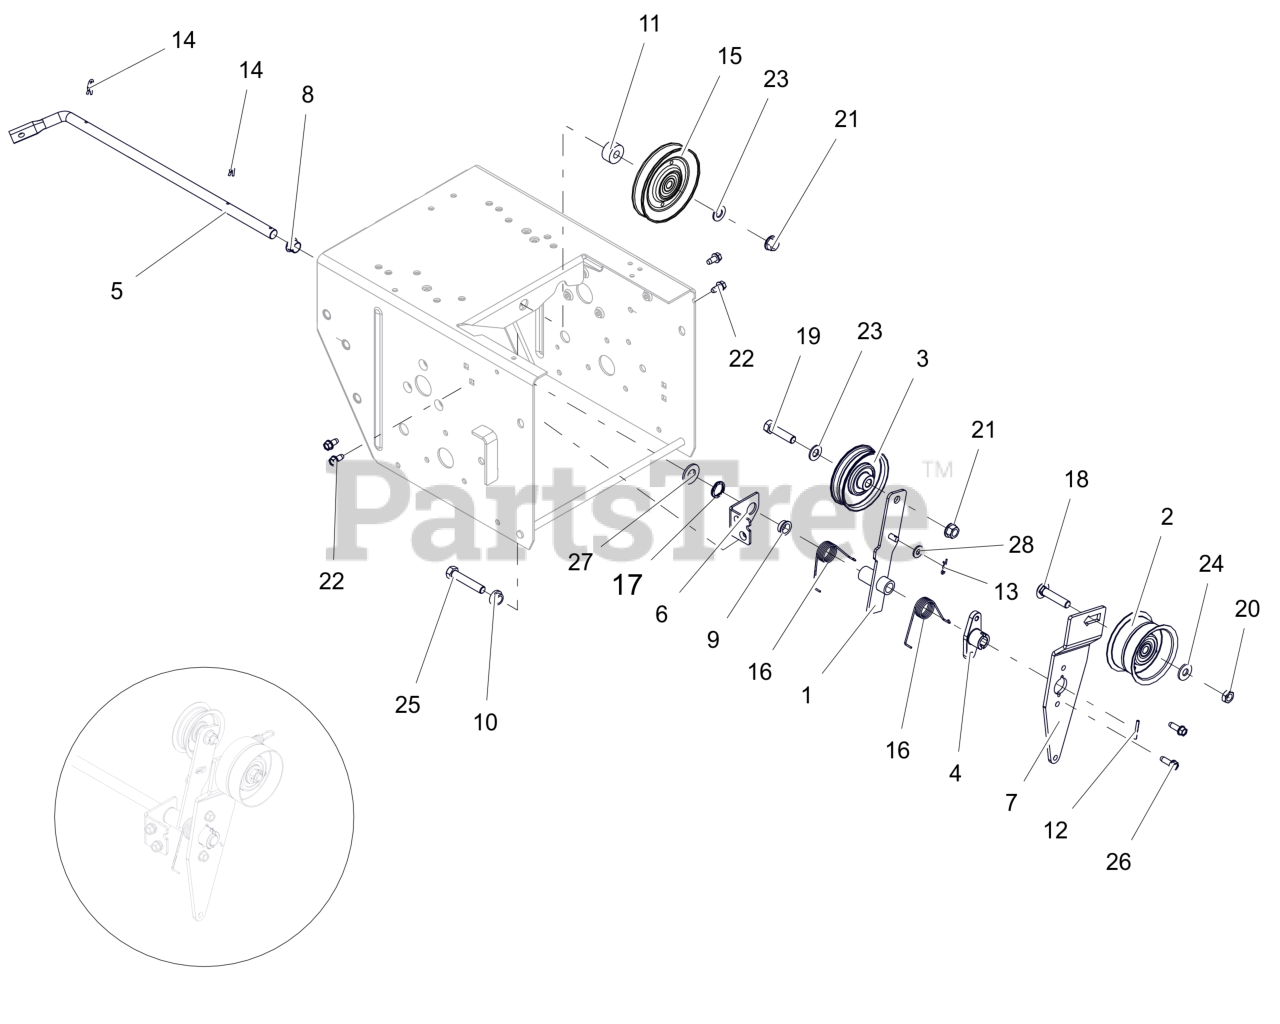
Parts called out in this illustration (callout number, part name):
1	ARM, TRACTION CLUTCH
2	IDLER, FLANGE -2.75 OD X .375 ID
3	IDLER, FLAT - 3.000" X .750"
4	HUB, BRAKE ARM
5	ARM, ATTACHMENT
6	BRACKET, SUPPORT
7	ARM- IDLER-ATTACHMENT
8	BUSHING, POLYLINER-.50 SPLIT
9	BSHG,FLANGE .500X.625X.270X.75
10	BSHG, FLANGE .391X.56X.313X.75
11	BSHG,POCKET .391X.570X1.0X.450
12	PIN-ROLL .125X1.00
13	PIN, HAIR #178 .06X.77 ZCC
14	CLIP, SPRING
15	SHV, .38"ID X 4.00"OD V-IDLER
16	SG-TORS .067X.88
17	WAVE SPRING .600X.875X.25FH
18	BLT, RHSSN .38-16X1.75 G5 ZCC
19	BLT, HEX .38-16X1.50 G5 ZCC
20	NUT-LK-CTR-JAM .375-16 GB ZCC
21	NUT-LK-TOP-FLG .38-16 ZC120
22	SCR-TAP .25-20X.50 HWH ZCC
23	WSHR,FLT .406X.812X.065 ZCC
24	WSHR,FLT .375X.875X.083 ZCC
25	BLT,HEX .38-16X2.00 G5 ZCC
26	SCR,TAP .25-20X.75 HWH TR ZCC
27	WSHR,FLT .531X1.062X.095 ZCC
28	WSHR,FLT .281X.625X.065 ZCC
